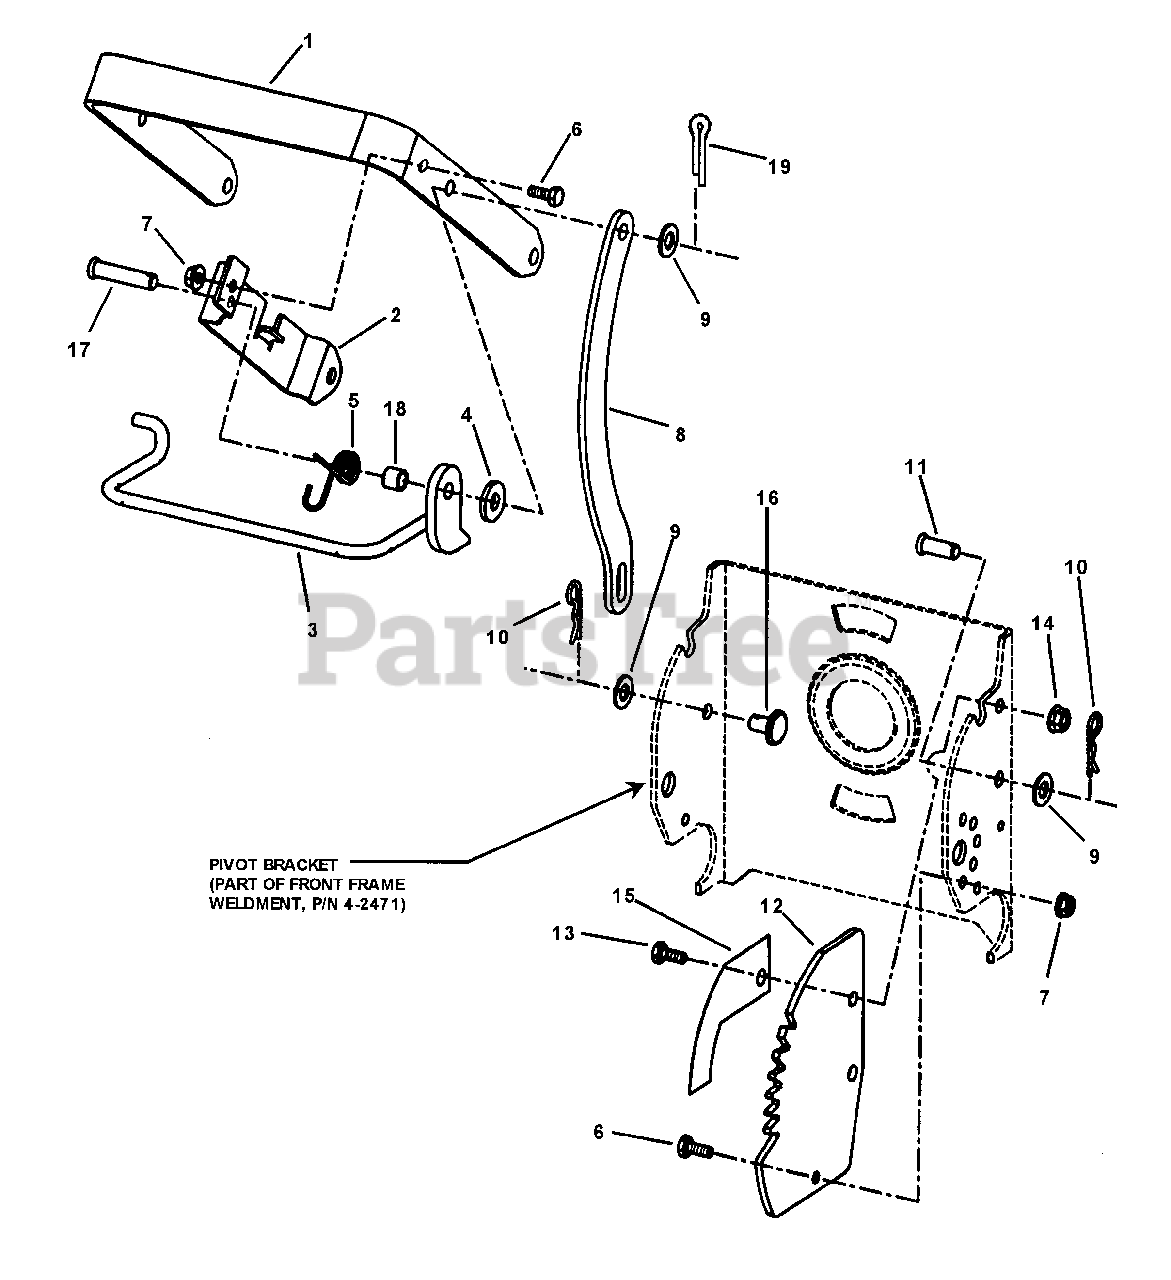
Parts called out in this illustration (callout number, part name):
1	HANDLE, Deck Lift
2	BRACKET, Pivot Support
3	LEVER, Deck Lift/Handle Release
4	WASHER, Slipper
5	SPRING, Torsion (Deck Position)
6	SCREW, 1/4-20 x 5/8" Hex head Cap, Gr. 5
7	NUT, 1/4-20 Hex Flange Lock
8	BAR, Deck Lift
9	WASHER, 3/8" Flat
10	HAIRPIN, 3/32 x 1-1/2"
11	PIN, 3/8 x 7/8" Large Head Clevis
12	PLATE, Detent
13	SCREW, 5/16-18 x 3/4" Hex Cap, Gr.5
14	NUT, 5/16-18 Hex Flange Lock, Gr.5
15	DECAL, Deck Position
16	PIN, 3/8 x 1/2" Expanded Head Clevis
17	PIN, 3/8 x 1-5/8" Clevis
19	PIN, 3/32" x 3/4" Cotter
